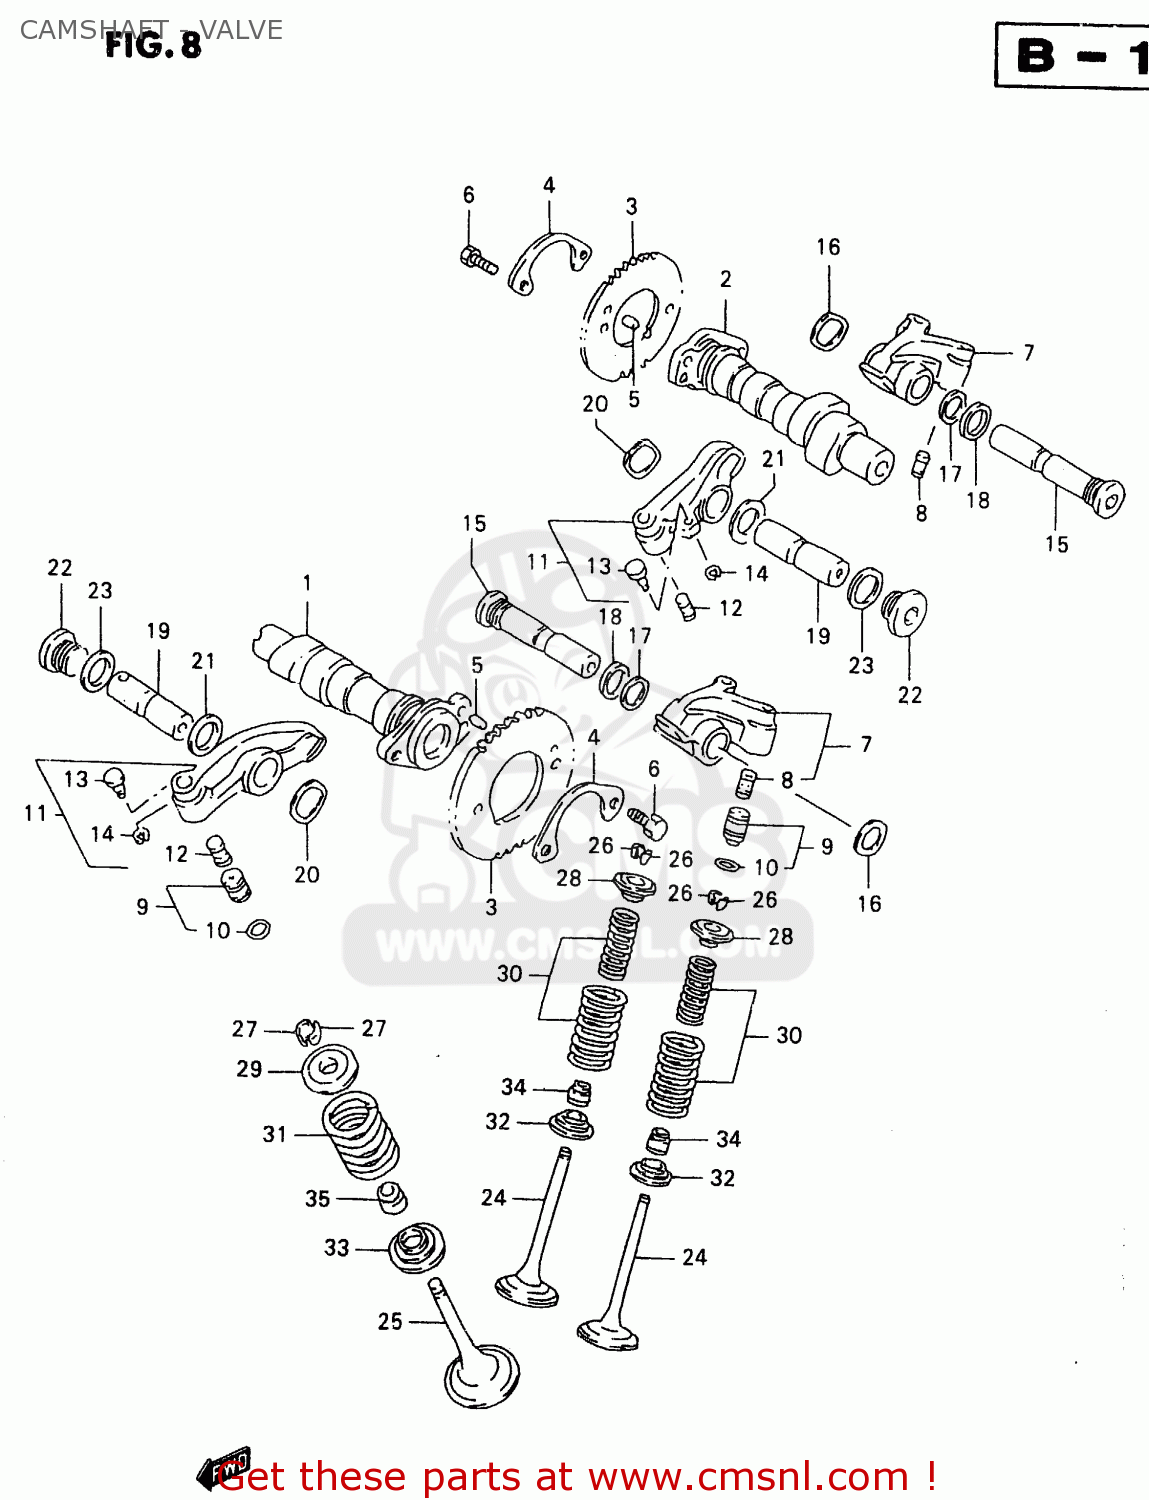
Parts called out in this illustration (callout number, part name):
1	CAMSHAFT,FR
2	CAMSHAFT,RR
3	SPROCKET,CAMSHAFT
4	WASHER,CAM CHAIN SPROCKET
5	PIN
6	BOLT(6X12.5)
7	ARM,VALVE ROCKER INTAKE
8	CHAMBER,VALVE LASH ADJUSTER
9	ADJUSTER,HYDRAULIC VALVE
10	O-RING,ADJUSTER
11	ARM,VALVE ROCKER FR EXHAUST
12	CHAMBER,VALVE LASH ADJUSTER
13	PIN,DECOMP
14	E RING
15	SHAFT,INTAKE VALVE ROCKER ARM
16	WASHER
17	SHIM(14X20X1)
18	GASKET(16X22X2) (NAS)
19	SHAFT,EXHAUST VALVE ROCKER ARM
20	WASHER
21	WASHER(16X26X1)
22	PLUG,18X11
23	GASKET(18X24.2X2) (NAS)
24	VALVE,INTAKE
25	VALVE,EXHAUST
26	COTTER,VALVE
27	COTTER,VALVE
28	RETAINER,VALVE SPRING
29	RETAINER,VALVE SPRING
30	SPRING SET,VALVE
31	SPRING,VALVE OUTER
32	SEAT,VALVE SPRING
33	SEAT,VALVE SPRING
34	SEAL,OIL(5.5X11X8.2)
35	SEAL,OIL(7X14.4X9)
